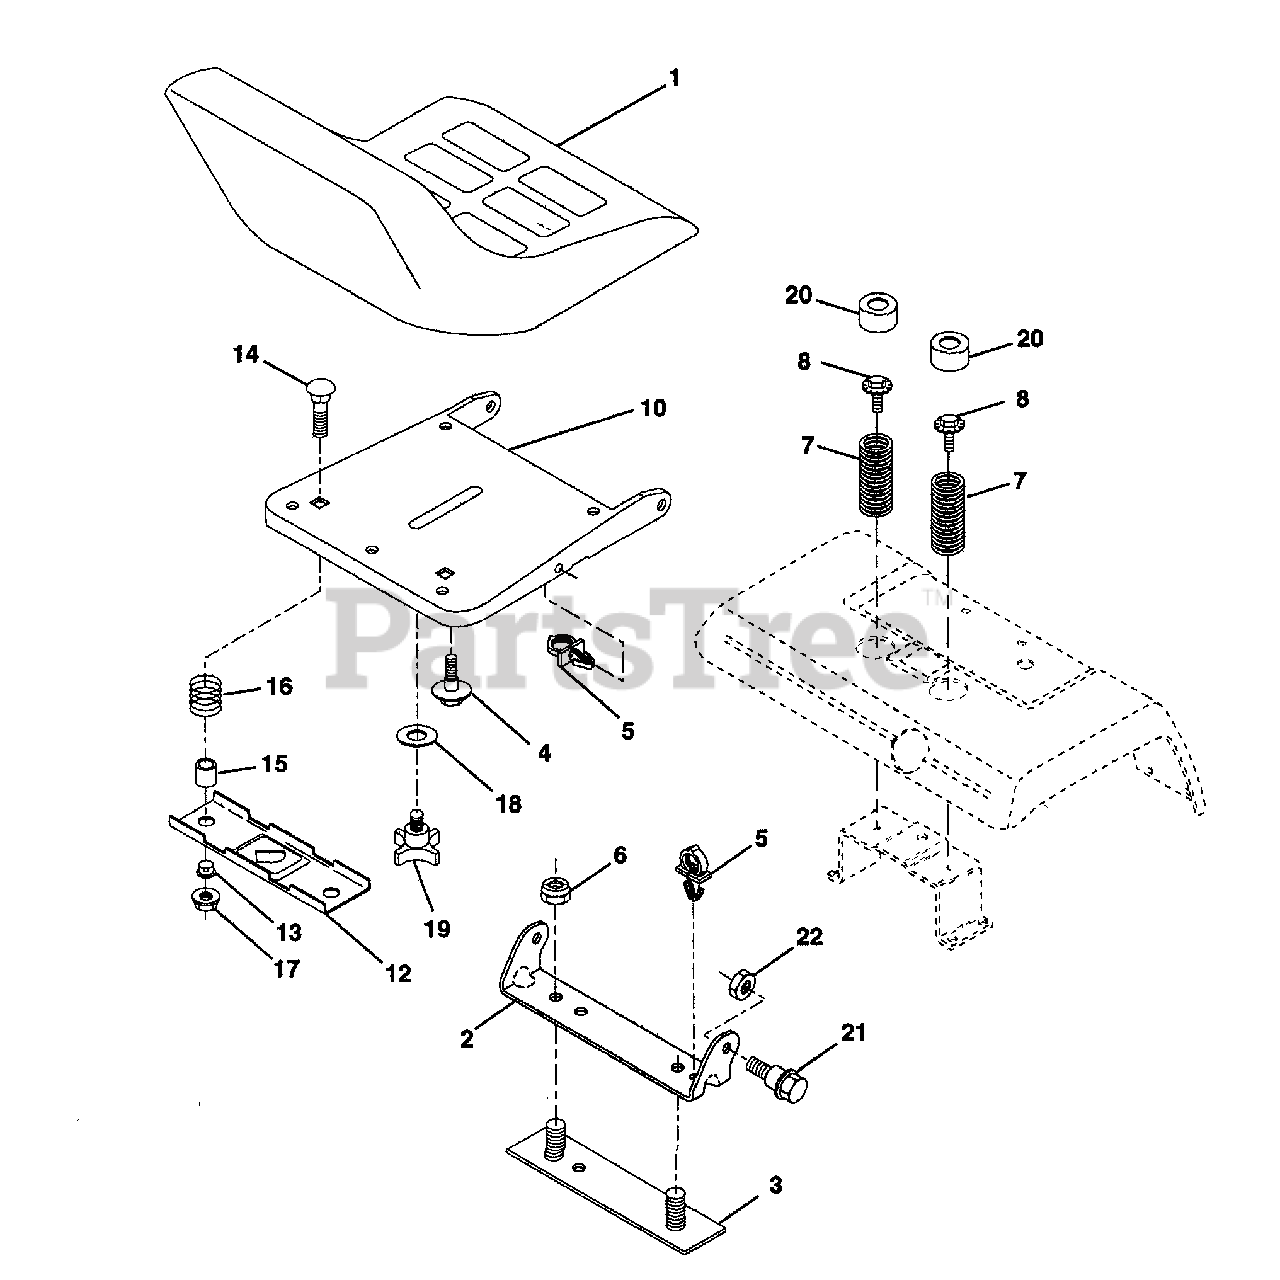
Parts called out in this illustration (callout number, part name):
1	Seat
2	Bracket, Pivot Seat
3	Strap, Fender
4	Bolt, Shoulder 5/16-18 X .62
5	Clip, Push In Hinged
6	Nut, Lock Hex W/Ins. 3/8-16 Unc
7	Spring, Seat Cprsn
8	Bolt 5/16-18unc x 3/4 W/Sems
10	Pan, Seat
12	Bracket, Mounting Switch
13	Bushing, Snap
14	Bolt, Carriage 1 /4-20 X 1-3/8
15	Spacer, Split
16	Spring, Cprsn
17	Nut, Lock 1/4 Lge Flg Gr. 5
18	Washer 17/32 X 1-3/16 X 12 Ga.
19	Knob, Seat 1/2-13 Unc
20	Cap, Spring Seat
21	Bolt, Shoulder 5/16-18 Unc-2A
22	Nut, Crownlock 5/16-18 Unc
